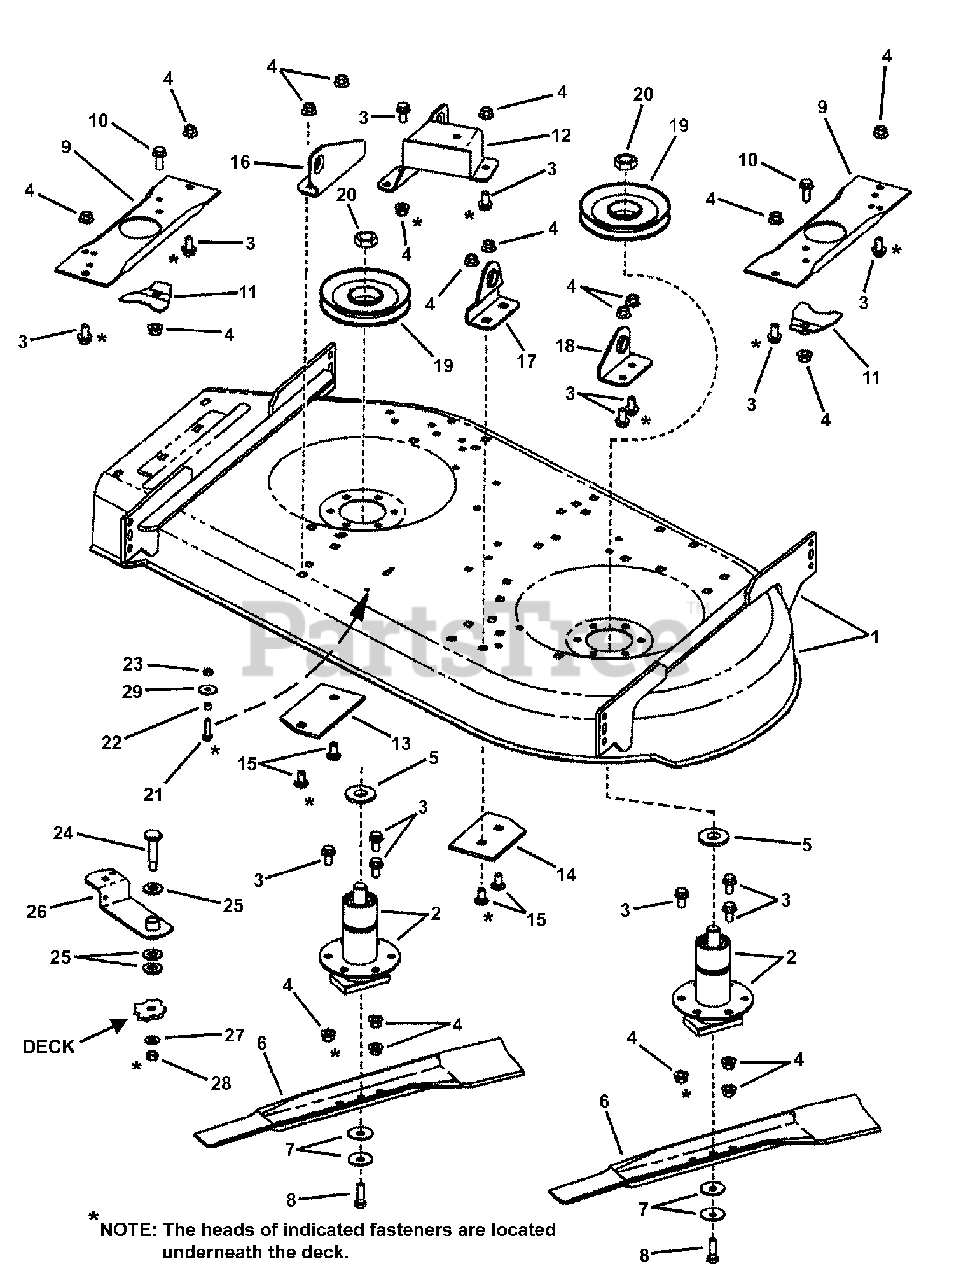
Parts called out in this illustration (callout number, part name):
1	DECK, 42" Replacement
2	ASSEMBLY, Spindle, Brake
3	BOLT, 3/8-16 x 3/4" Hex Flange Lock, GR 5
4	NUT, 3/8-16 Hex Flange Lock
5	WASHER, Spindle
6	BLADE, 21" Standard Lift
7	WASHER, .406 I. D. Cone
8	SCREW, 3/8-24 x 1-1/4" Hex Head Cap, GR 5
9	BRACE, Spindle
10	BOLT, 3/8-16 x 1" Hex Flange Lock, GR 5
11	ASSEMBLY, Spindle Lock
12	WELDMENT, Stationary Idler, 42 HOZ
13	REINFORCEMENT, 42" Deck, RH
14	REINFORCEMENT, 42" Deck, LH
15	BOLT, 3/8-16 x 3/4" Short Neck Carriage, GR 5
16	BRACKET, Right Front Lift, 42" Deck
17	BRACKET, Left Front Lift, 42" Deck
18	BRACKET, Left Rear Lift, 42" Deck
19	PULLEY, 5-1/4"
20	NUT, 3/4-16 Hex Jam, GR 8
21	BOLT, 1/4-20 x 1-1/8" Hex Flange Lock, GR 5
22	SPACER, .265 x .375 x .300 Thick
23	NUT, 1/4-20 Hex Center Lock, GR 5 or B
24	BOLT, 3/8-24 x 5/8" Shoulder
25	WASHER, .531 x 1.062 x .121 SAE Flat
26	WELDMENT, Idler Arm, 42" HOZ
27	WASHER, 3/8" SAE Flat
28	NUT, 3/8-24 Hex Center Lock GR 5 or B
29	WASHER, 1/4" Flat
